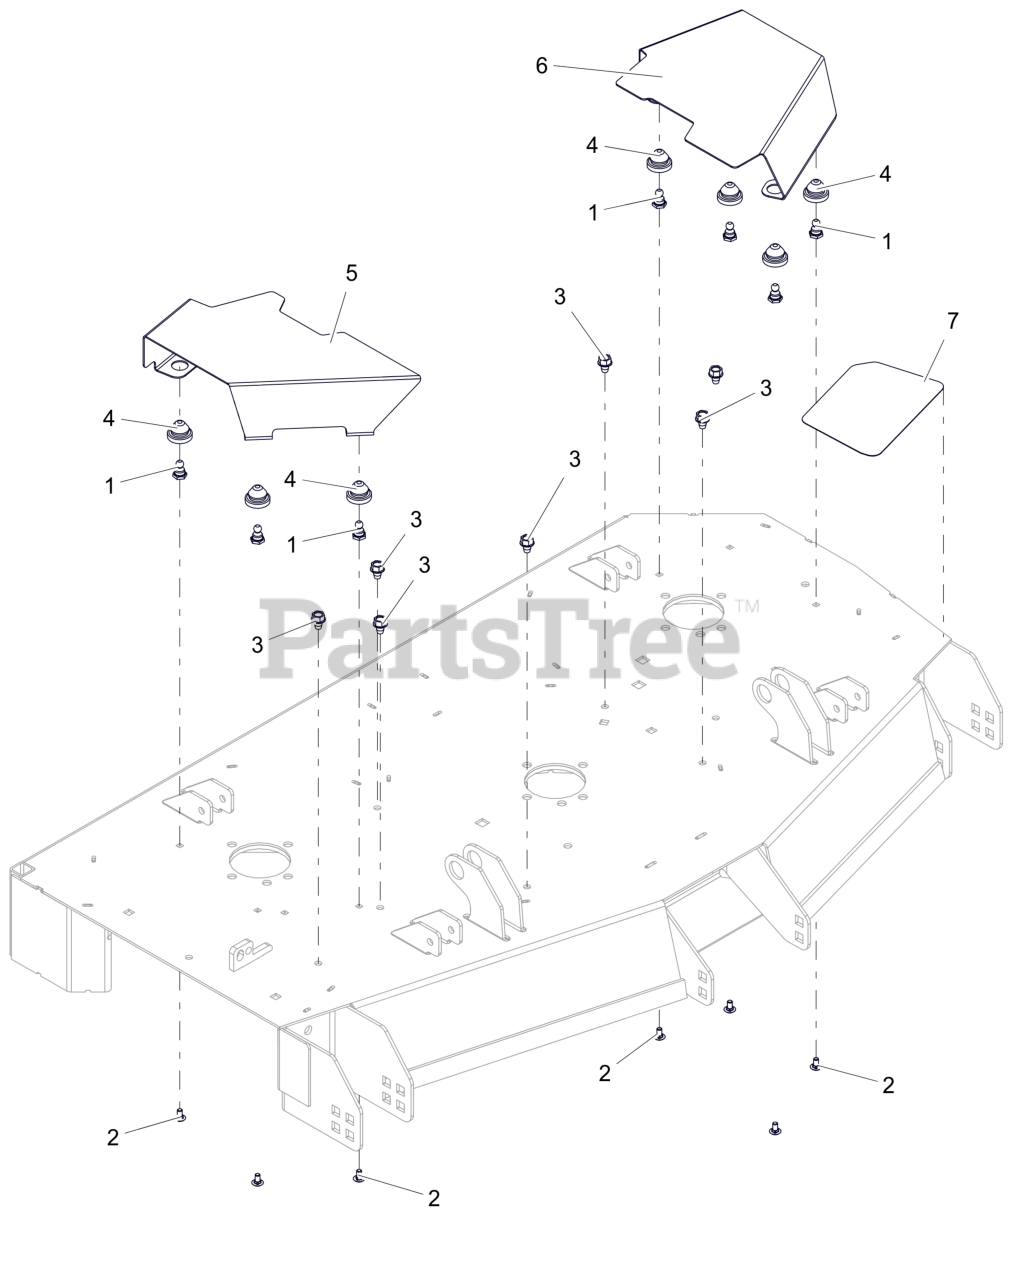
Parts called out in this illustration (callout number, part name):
1	STUD, BALL FEMALE .250-20 THREAD
2	BLT, RHSSN.25-20X.500 G5 ZCC
3	SCR,TAP .375-16X.50 HWH TR ZCC
4	COUPLING, RUBBER PUSH-IN
5	COVER- BELT 48" RIGHT
6	COVER- BELT 48" LEFT
7	GRIP, STEP ANTI SKID HD XF3
